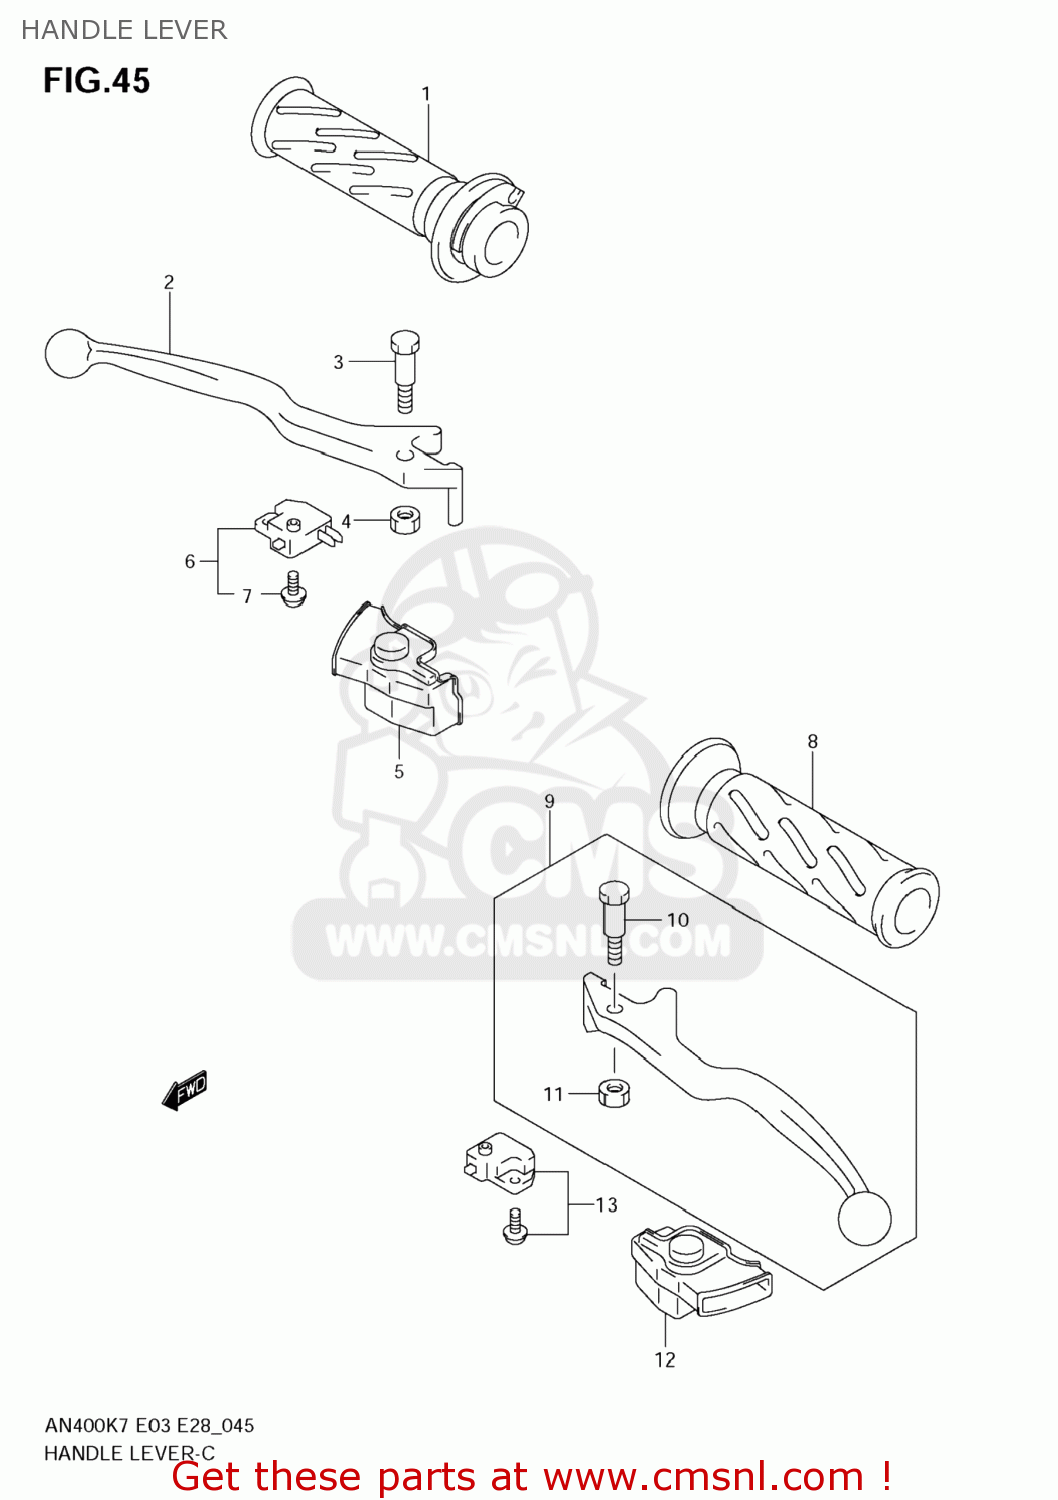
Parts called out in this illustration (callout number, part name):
1	GRIP,THROTTLE
2	LEVER,FR BRAKE
3	BOLT,BRAKE LEVER PIVOT
4	NUT,LEVER PIVOT
5	COVER,BRAKE LEVER,R
6	SWITCH ASSY,ST
7	SCREW
8	GRIP,LEFT
9	LEVER ASSY,RR BRAKE
10	BOLT,BRAKE LEVER PIVOT
11	NUT
12	COVER,BRAKE LEVER,L
13	SWITCH ASSY,RE
